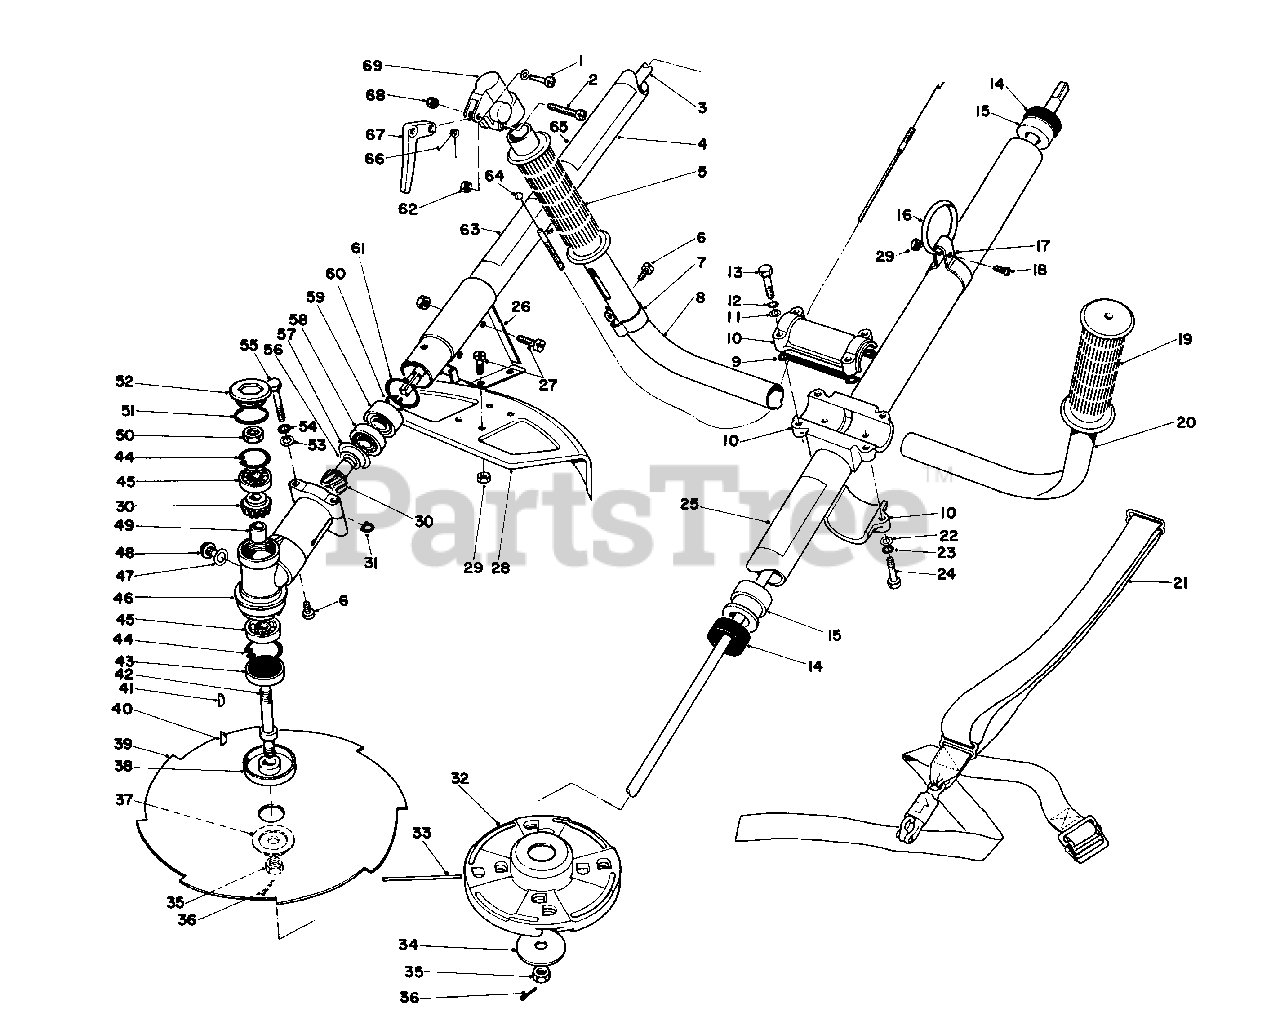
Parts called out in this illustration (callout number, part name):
2	Screw w/Washer
3	Shaft, Driving
4	Housing Drive Shaft (Incl. Ref. #25 & 26)
5	Right Hand Grip
8	Handle R.H.
9	Shim Washer
10	Bracket Assembly, Handle (Incl. Ref. #9-13 & 22-24)
12	Spring Washer
16	Ring-Harness
17	Clamp-Harness
19	Left Hand Grip
20	Handle L.H.
21	Shoulder Strap, Deluxe
22	Washer
23	Spring Washer
25	Decal-Warning
26	Bracket Shield
28	Head Guard
30	Gear Set
32	Cutter Head
33	.105 Filament Line, Pkg. of 24
34	Plate, Nylon Head
36	Cotter Pin
37	Blade Adapter Kit (Incl. Ref. #35 & 36)(optional)
38	Plate, Blade Fixing
39	8 Tooth Blade
40	Woodruff Key
41	Woodruff Key
42	Shaft, Power Take Off
43	Oil Seal
45	Ball Bearing
46	Housing, Gear
51	'O'-Ring
52	Lid, Gear Housing
54	Spring Washer
58	Ball Bearing
59	Ball Bearing
62	Nut
63	Decal-TC800
64	Throttle Cabel
65	Decal-Warning
66	Return Spring
67	Throttle Trigger
69	Bracket, Throttle Trigger
